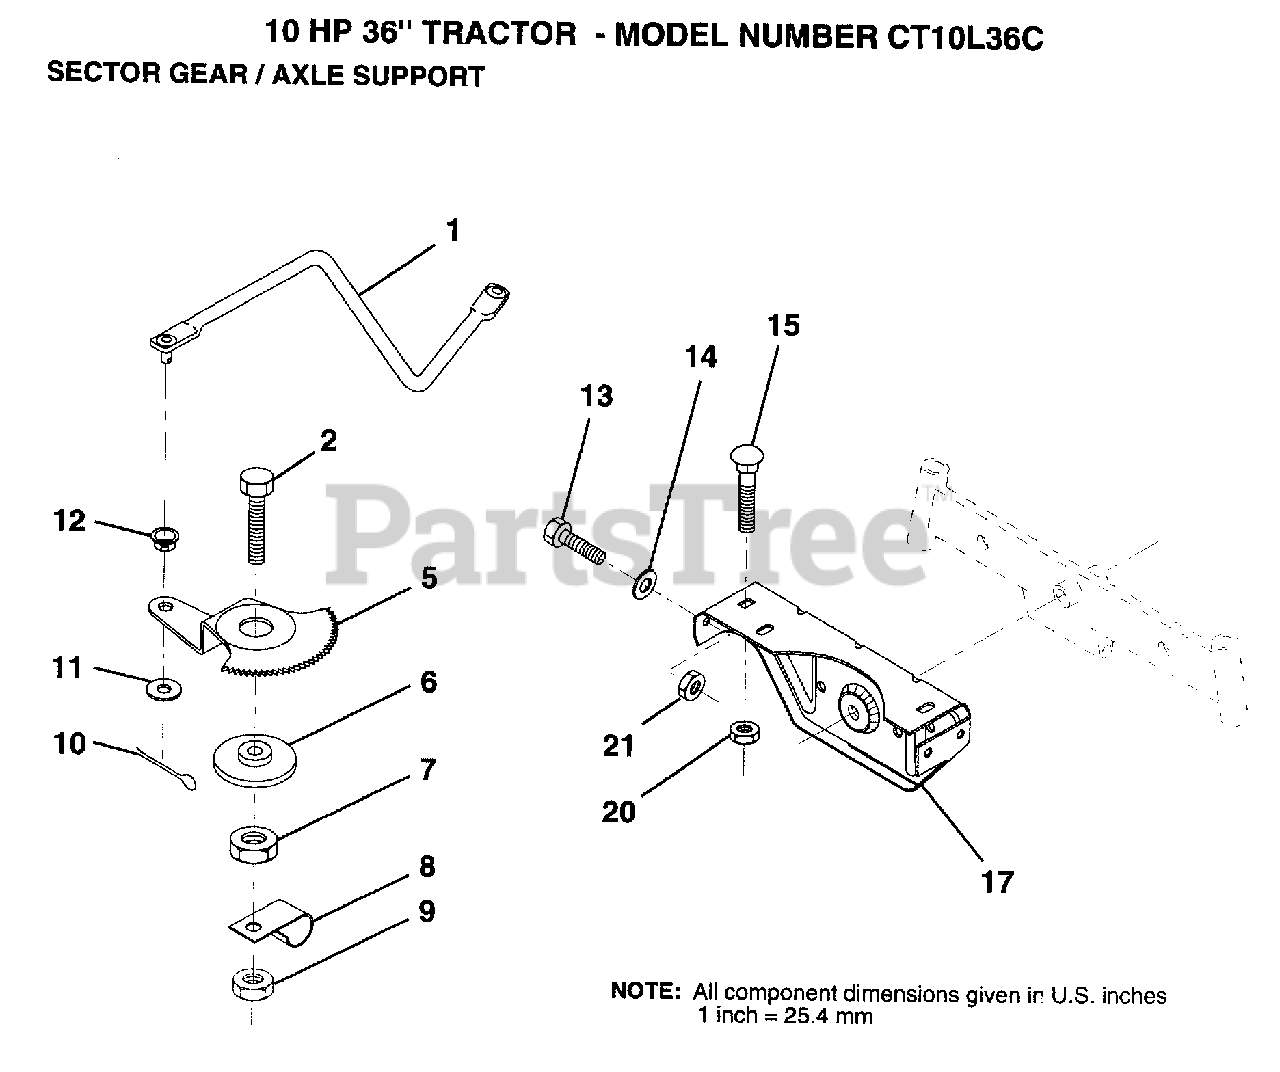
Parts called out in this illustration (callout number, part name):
1	DRAG LINK
2	"BOLT,HEX"
5	GEAR SECTOR
6	BUSHING
7	NUT
8	CLIP INSULATOR
9	NUT LTV
10	COTTER PIN
11	WASHER
12	BUSHING.DRAGLINK
13	BOLT
14	WASHER
15	BOLT
17	SUPT AXLE FRONT
20	NUT
21	NUT
